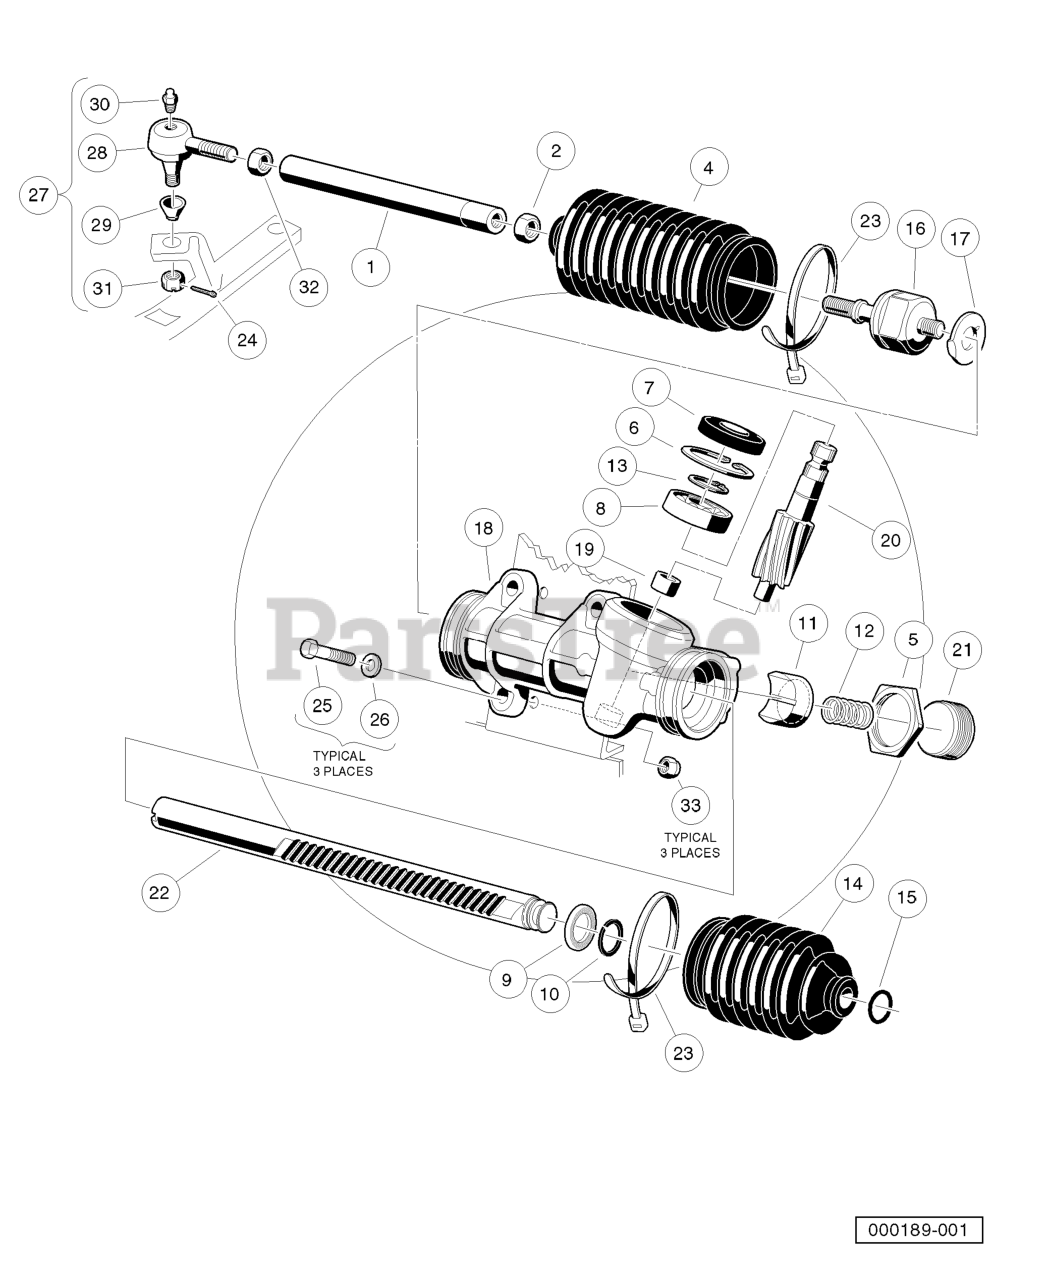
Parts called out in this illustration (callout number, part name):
1	DRAG LINK RACK & PINION
2	12MM HEX NUT
3	ASM, STEERING RACK, 3.13
4	BELLOWS, LONG
5	RACK SCREW LOCKNUT
7	SEAL, STEERING PINION DUST
8	BEARING BALL
9	STOP WASHER
10	STOP RING C - TYPE
11	SUPPORT YOKE
12	RACK GUIDE PRESSURE SPRING
13	C-TYPE STOP RING
14	BELLOWS, SHORT
15	DUST SEAL RETAINING RING
16	INNER BALL JOINT ASM
17	WASHER, TAB
18	Box, Steering Gear
19	Bearing, Lower Pinion
20	Pinion, Steering
21	Screw, Rack Guide
22	Rack, Steering
23	TIE WRAP, 8" NYLON
24	PIN,CUT COTTER
25	SCREW, 3/8-16 X 1.5 HX HD CAP
26	WASHER, 3/8 FLAT
27	BALL JOINT, LH
28	Socket, LH Vertical
29	SEAL, VERTICAL SOCKET DUST
30	FITTING, 1/4-28 THRD FRM GREAS
31	NUT, 3/8-24 UNF HEX THICK SLOT
32	NUT, 1/2-20 HEX
33	LOCKNUT, 3/8-16 HEX
